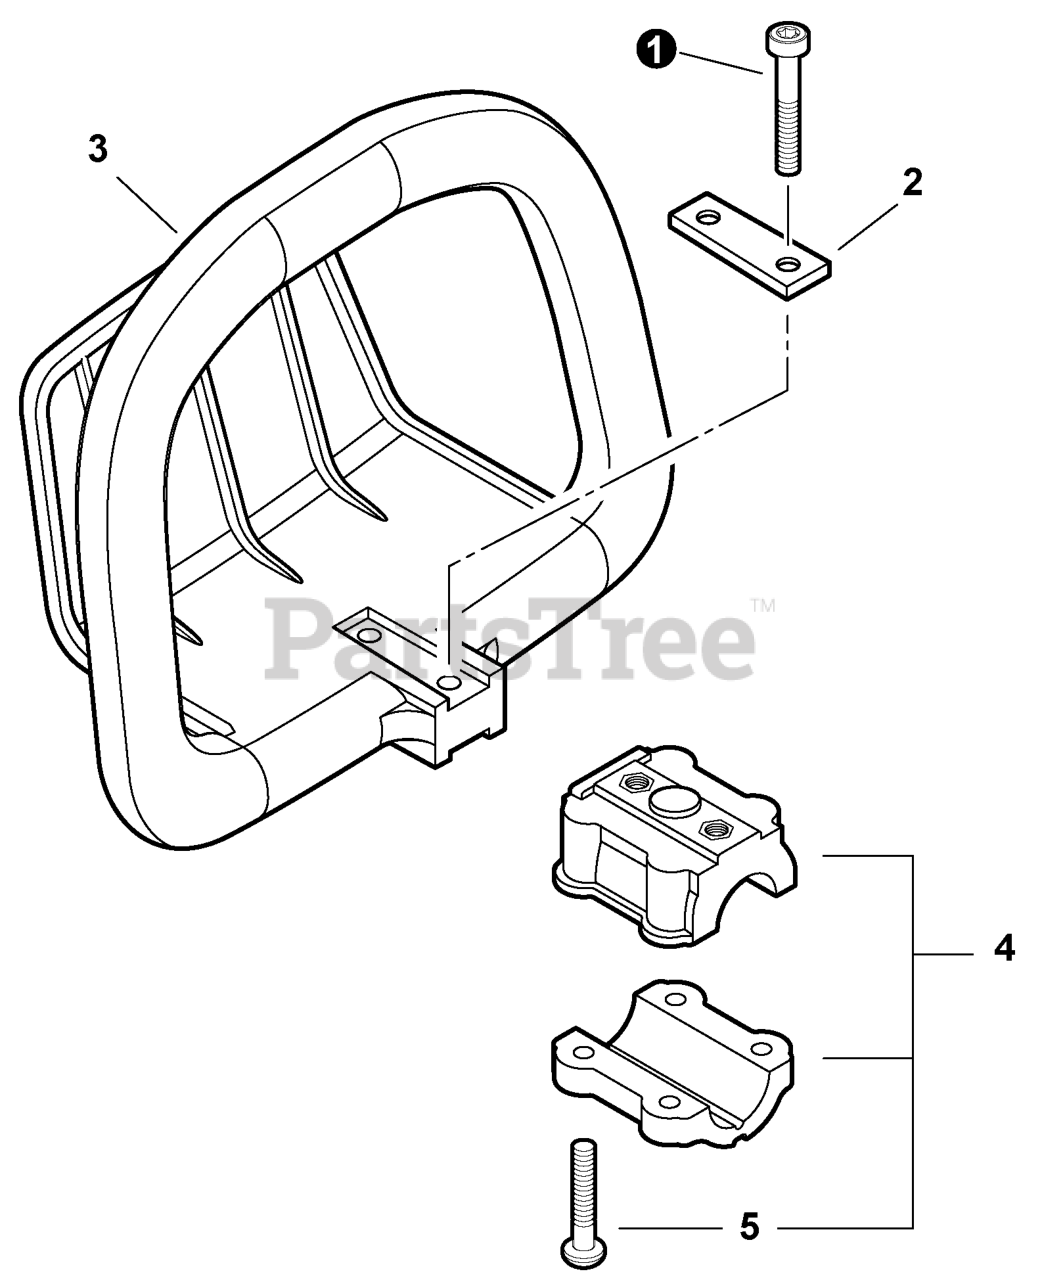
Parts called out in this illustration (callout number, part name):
1	BOLT, TORX 5x30
2	PLATE, EYE
3	HANDLE, SUPPORT
4	BRACKET KIT, HANDLE
5	BOLT, TORX 5x25
